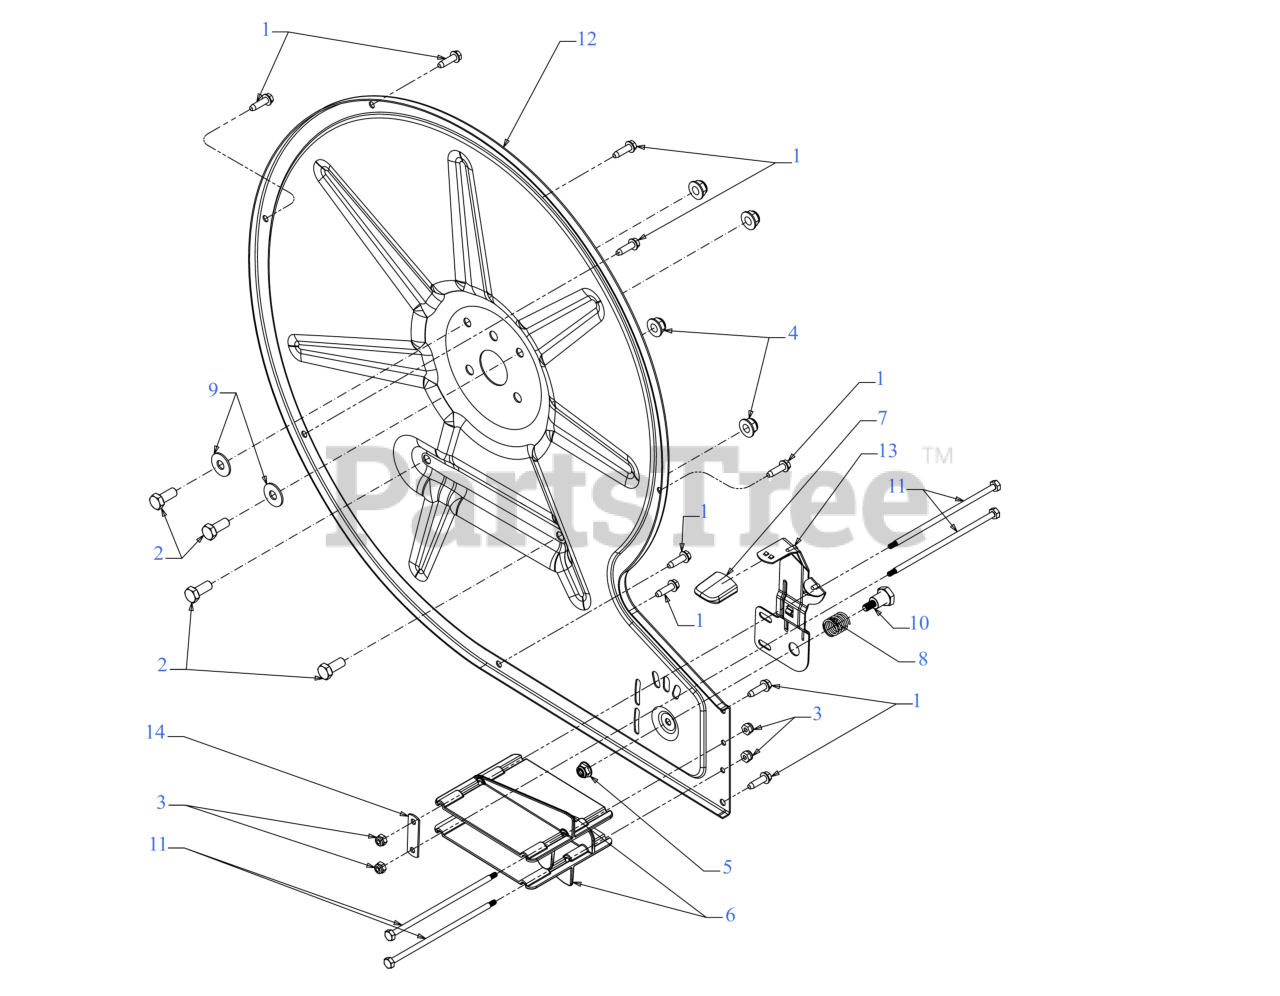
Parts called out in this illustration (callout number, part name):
1	SCREW #12-16 .75
2	SCREW 5/16-18 x .75 GR5
4	FLANGE LOCK NUT 5/16-18
5	FLANGE LOCK NUT
6	LOUVER BLOWER PLATE
7	HEIGHT ADJUSTMENT KNOB
8	COMPRESSION SPRING
9	BELL WASHER .337 X.867 x .057
10	SHOULDER SCREW .437X.50 1/4-20
11	SHOULDER SCREW 18 x 4.8 8-32 GR5
14	GUIDE LOUVER PLATE
